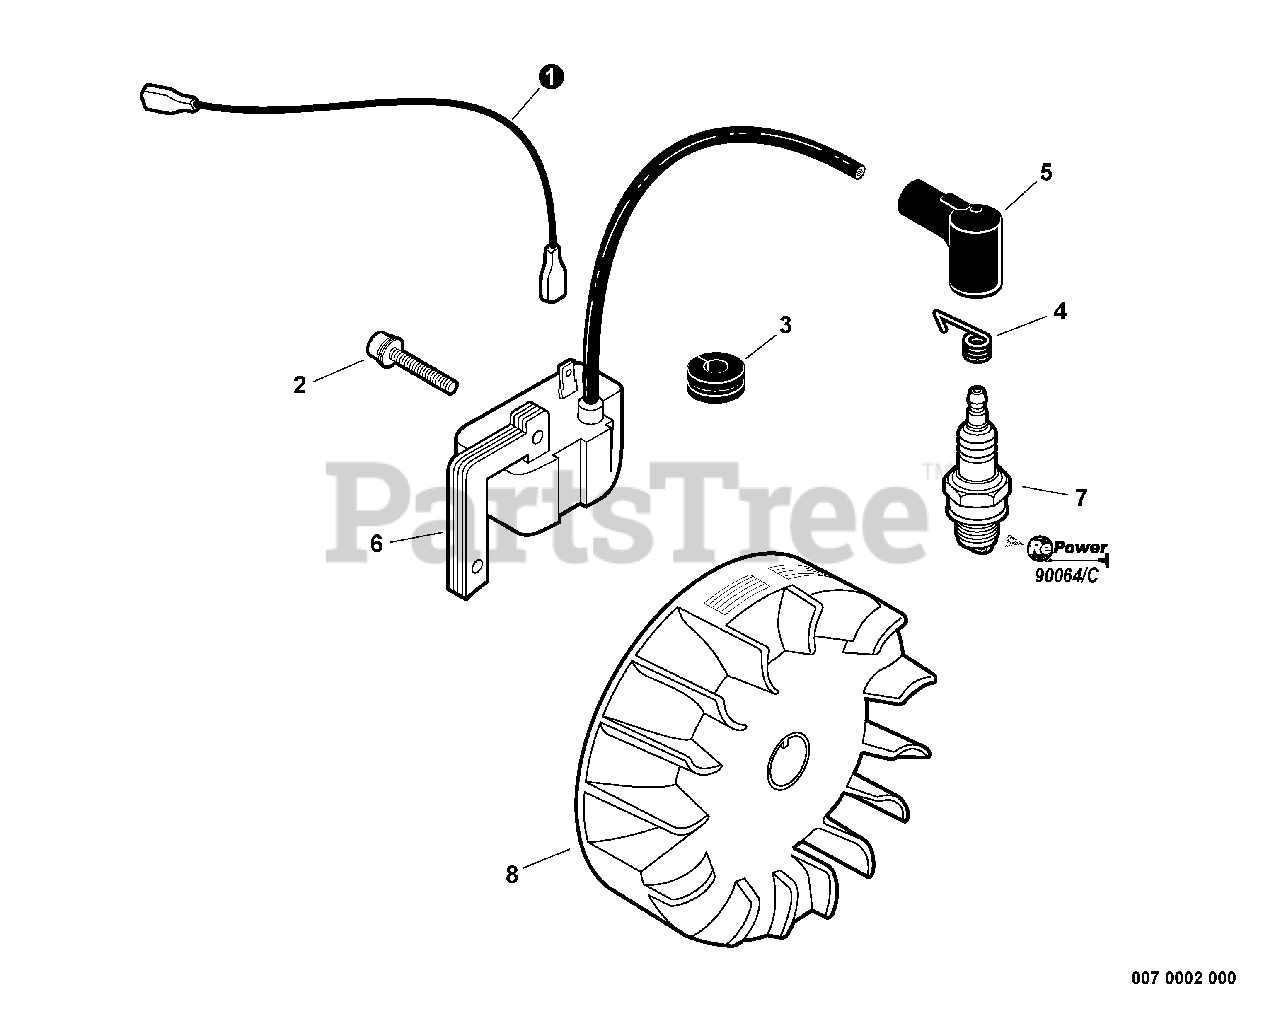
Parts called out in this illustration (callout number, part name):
1	LEAD
2	SCREW 4×22
4	TERMINAL, SPARK PLUG
5	CAP, SPARK PLUG
6	COIL, IGNITION
7	SPARK PLUG - BPM7A
7	SPARK PLUG - BPMR7A
9	TUNE-UP KIT
